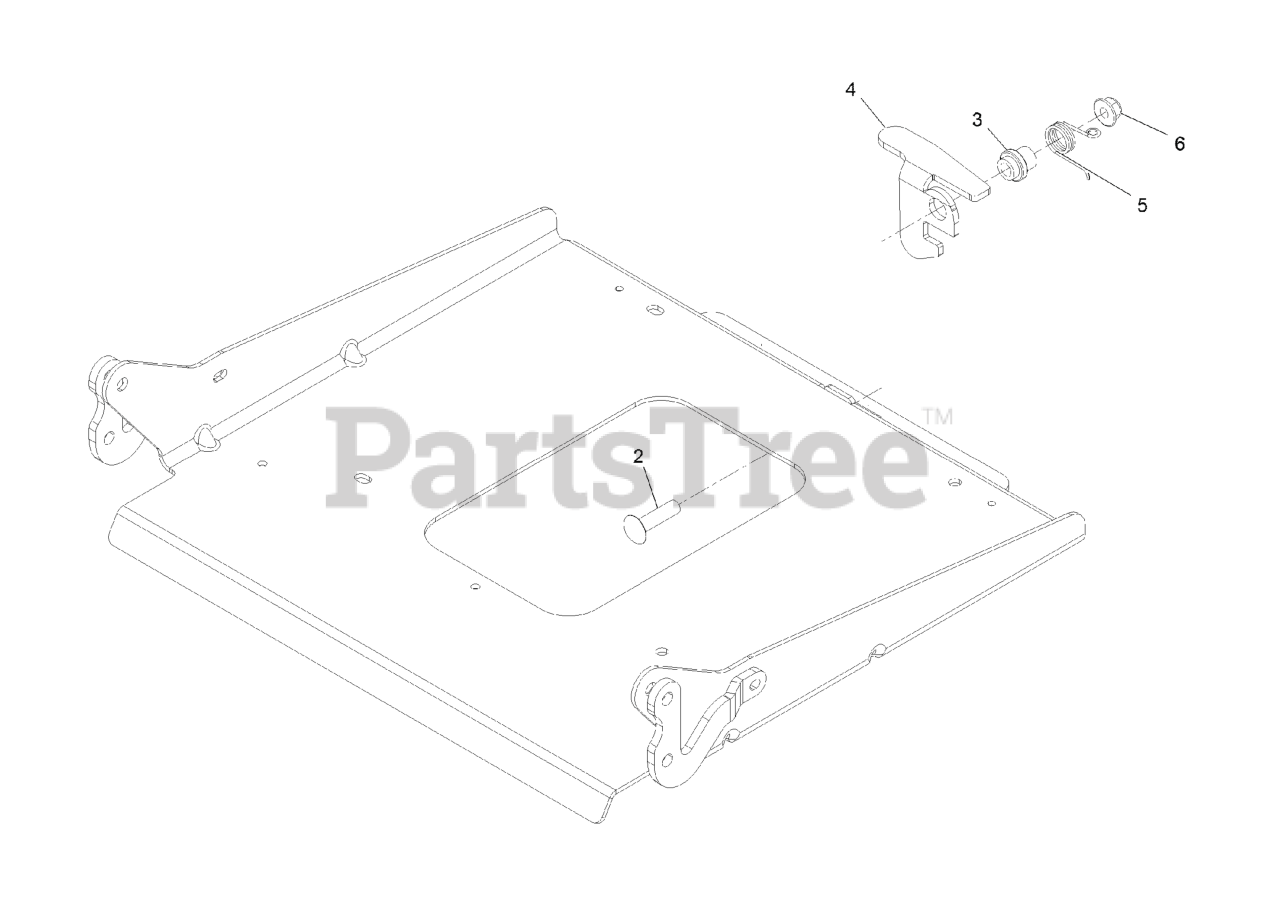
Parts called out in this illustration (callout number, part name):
2	SCREW-CARR
3	BUSHING-LATCH, SEAT
4	LATCH-CATCH, SINGLE
5	SPRING-TORSION, LATCH
6	NUT-HF, NI
